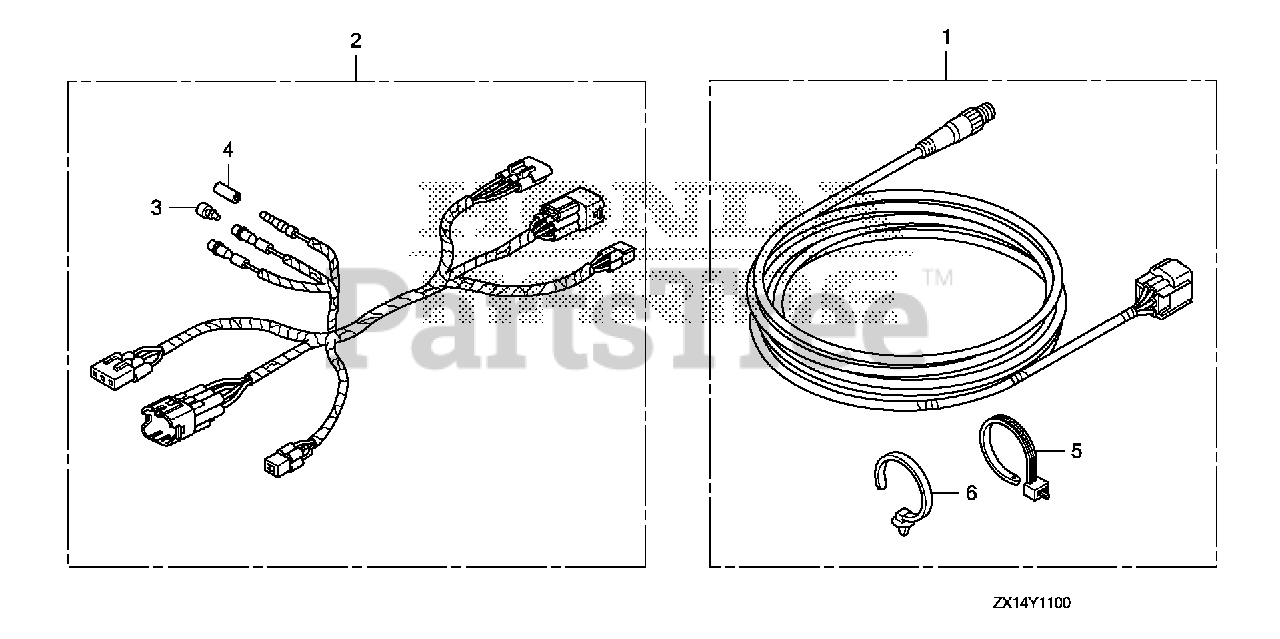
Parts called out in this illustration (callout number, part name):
1	KIT, CABLE (6FT) (NMEA)
2	HARNESS ASSY., REMOTE CONTROL SUB (ENGINE NO.)
3	PLUG, CONNECTOR (INNER) (TROLLING CONTROL)
4	PLUG, CONNECTOR (OUTER) (ENGINE NO.)
5	TIE, CABLE
6	CLIP, HARNESS BAND (155.3MM) (BLACK)
